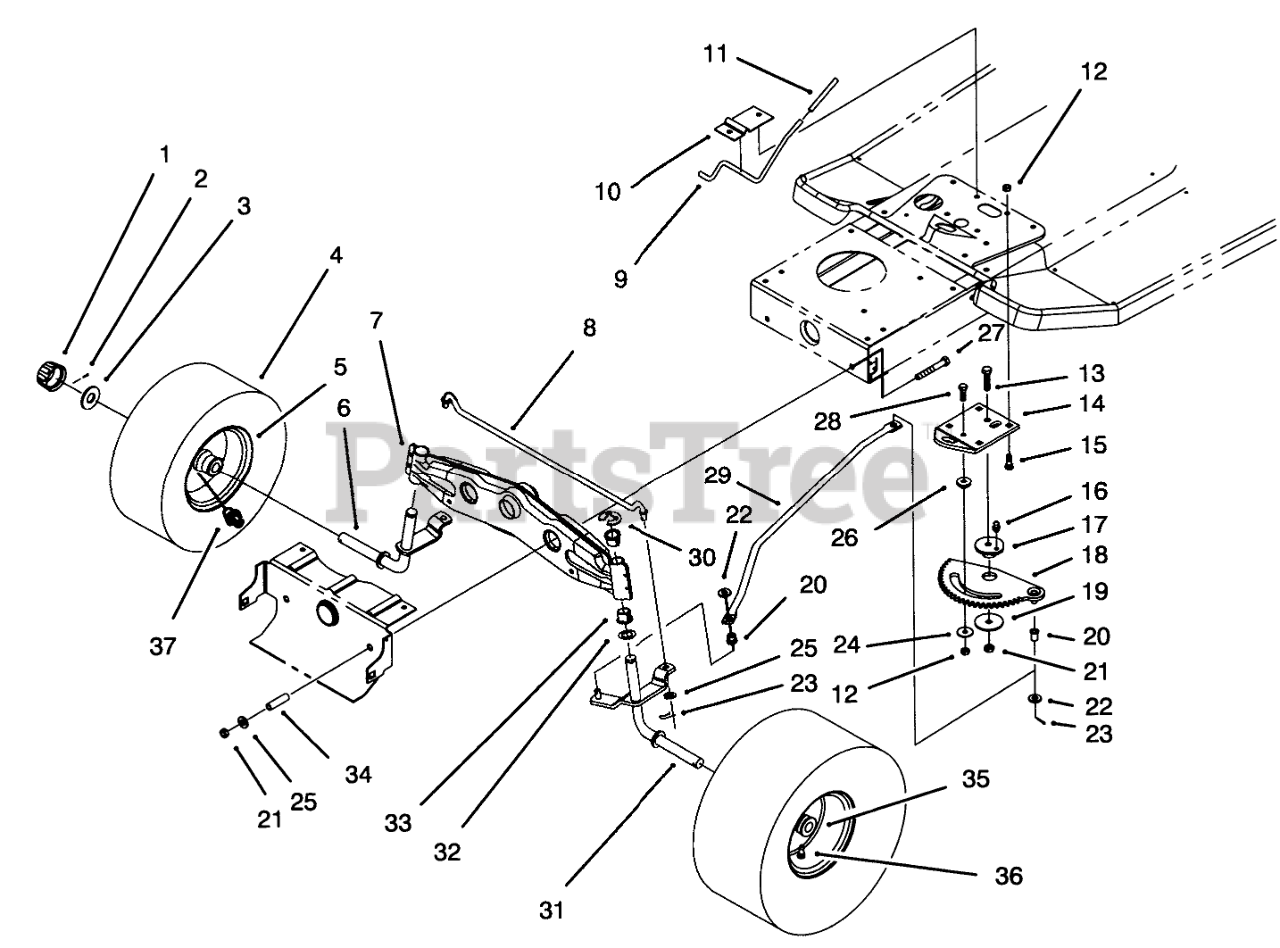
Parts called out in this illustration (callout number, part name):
1	CAP-HUB
2	PIN-COTTER
3	WASHER-PLAIN
4	TIRE 15 X 6.00 X 6
5	RIM ASM
6	Spindle-R.H.
7	Axle-Front
8	TIE ROD-STEERING
9	ROD-BRAKE, PARKING
10	Bracket-Parking Brake
11	GRIP-BRAKE, PARKING
12	NUT-LOCK, NI
13	SCREW-CARR
14	Bracket-Steering Rack
15	BOLT-CARR
16	FITTING-GREASE
17	BUSHING-ECCENTRIC
18	RACK-STEERING
19	WASHER-BEARING
20	BUSHING-FLANGED, NYLON
21	NUT-LOCK, NI
22	WASHER-FLAT
23	PIN-COTTER
24	WASHER-PIVOT
25	WASHER-FLAT
26	SPACER-RACK, STEERING
27	SCREW-HH
28	SCREW-CARR
29	LINK-DRAG
30	E-RING
31	Spindle-L.H.
32	WASHER-THRUST
33	BUSHING
34	SPACER
35	BEARING-WHEEL
36	STEM-VALVE
37	FITTING-GREASE
